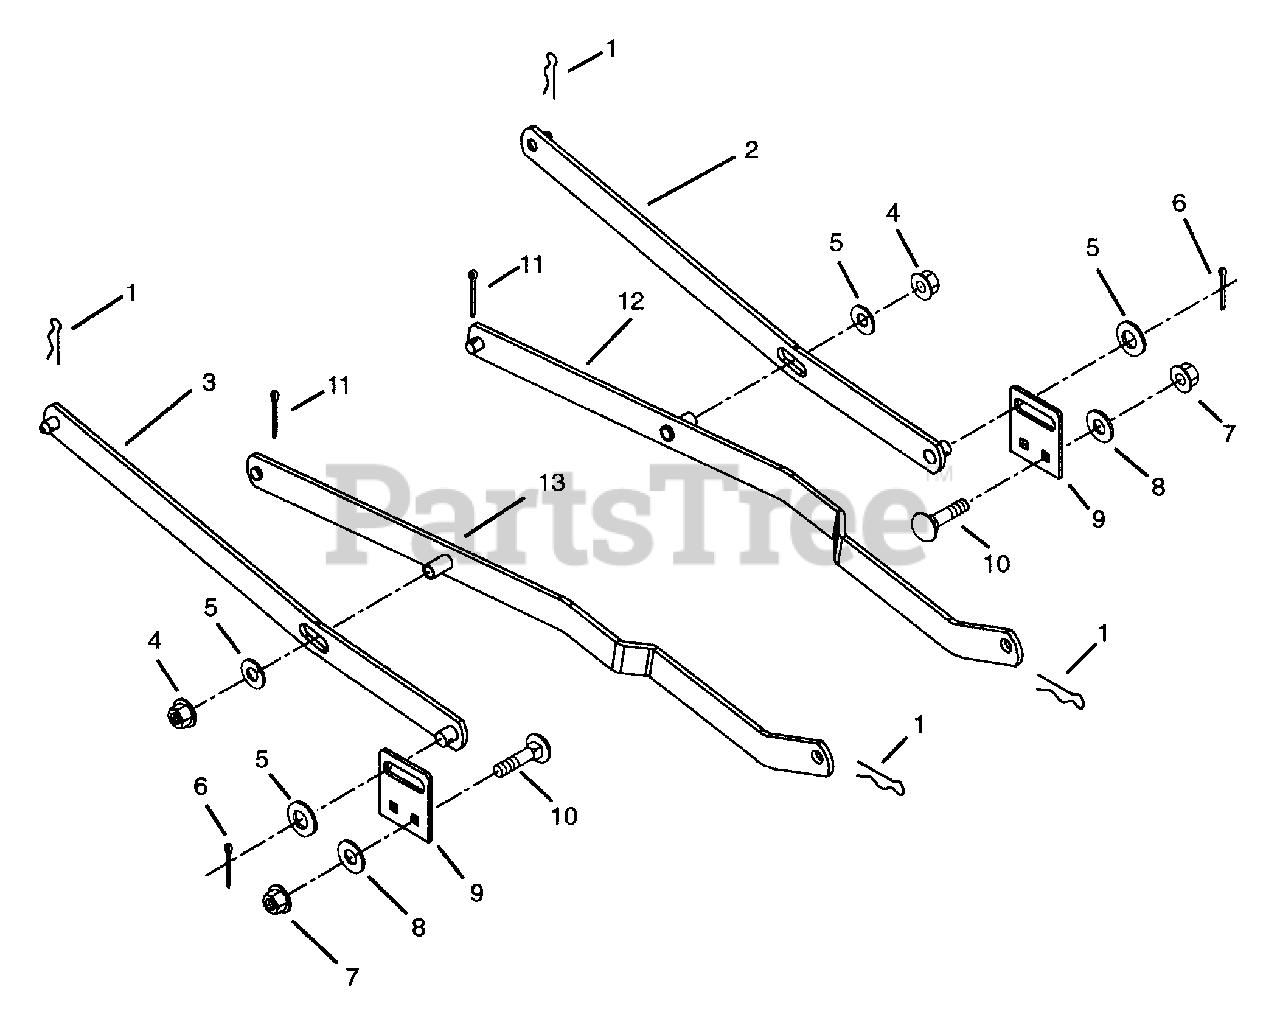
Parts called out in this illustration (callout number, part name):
1	PIN-HAIR EXT .12X.31X2.37 PL
2	ARM, LIFT-LEFT REAR
3	ARM, LIFT-RIGHT REAR
4	NUT-LK-CTR .625-11 TYP N
5	WSHR-FL-STL.656X1.312X.095 PL
6	@PIN-CTR .16X1.25 EXTPRSQCT YZ
7	NUT-LK-NYL .375-16 PL
8	WSHR-FL-STL.406X.812X.065PL
9	ADJUSTOR, PAN
10	BLT-RDHDSQNK .375-16X.75 GR5PL
11	PIN-COTR .12 X 1.25 PL
12	ARM, LIFT - LEFT FORWARD
13	ARM, LIFT - RIGHT FORWARD
